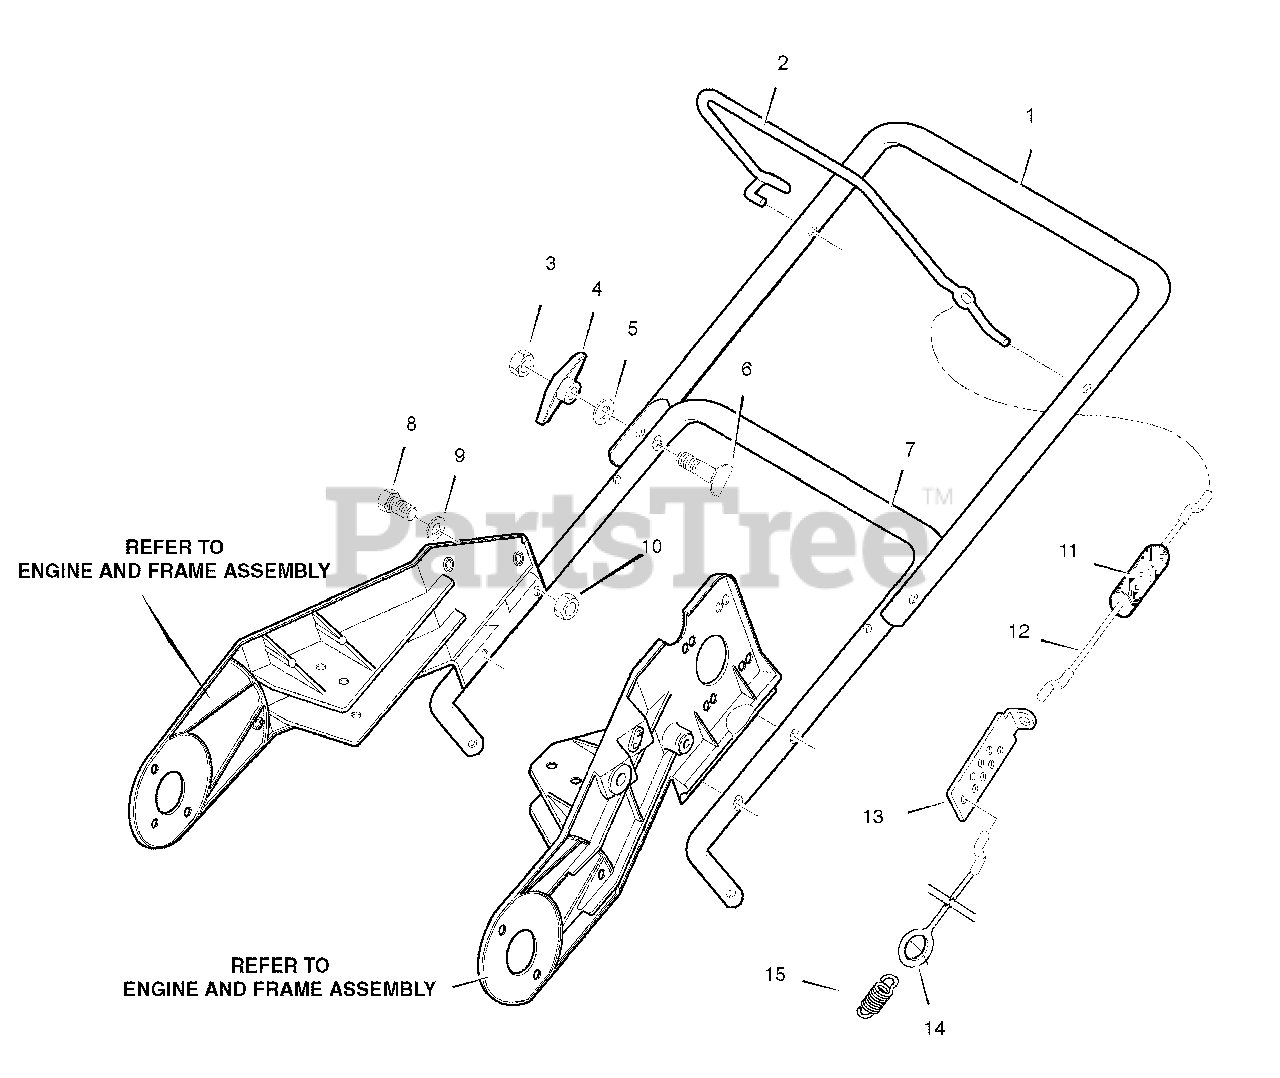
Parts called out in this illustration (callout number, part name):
1	HANDLE, Upper
2	BAIL, Control
3	NUT, Hex, 5/16-18
4	KNOB, Wing, 5/16-18
5	WASHER, Formed, 11/32 x 1 OD
6	BOLT, Carrigae, 5/16-18 X 2
7	HANDLE, Lower
8	CAPSCREW, 1/4-20 x 1-1/4
9	WASHER, Flat, 9/32 x 5/8 OD
10	NUT, Hex, 1/4-20
11	BOOT, Clutch Spring
12	CABLE, Upper Control
13	BRACKET, Cable Adjust
14	CABLE, Lower Control
15	SPRING, Extension
